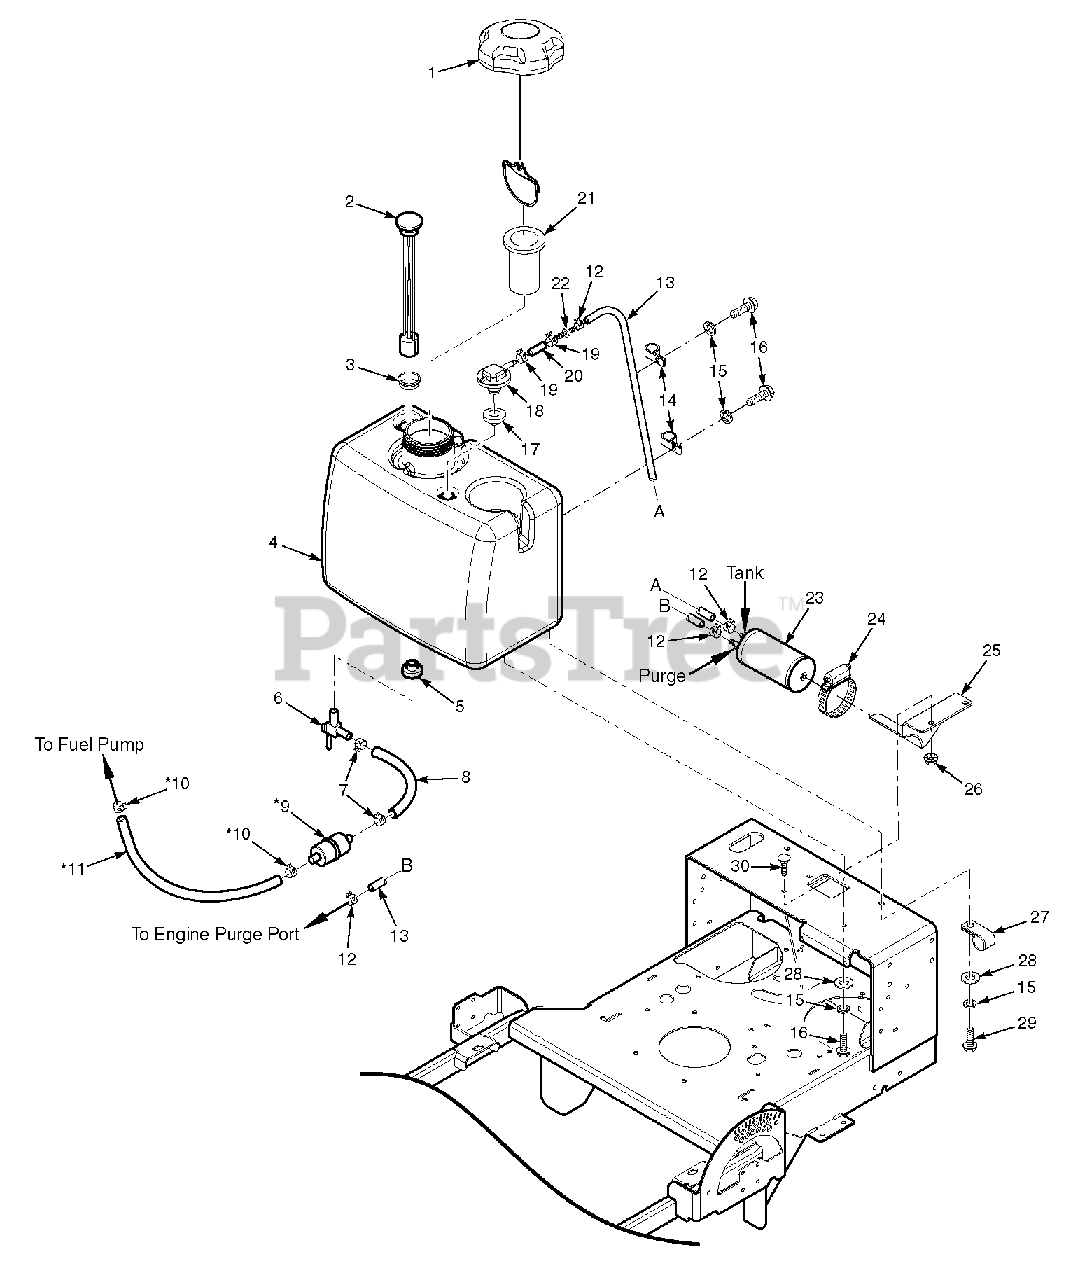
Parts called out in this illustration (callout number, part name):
1	Fuel Cap w/ Tether
2	Fuel Gauge Assembly
3	Seal, Fuel Gauge
4	Fuel Tank Assembly
5	Bushing, .56 Dia. Viton
6	Ball Valve w/Screen
7	Clamp, Fuel Hose
8	Fuel Hose, 1/4" ID
9	Fuel Filter
10	Clamp, Fuel Hose
11	Fuel Hose
12	Clamp, Vapor Recovery Hose 3/16"
13	Hose, Vapor Recovery 3/16"
14	Clamp, 3/8"
15	Lockwasher, 5/16" Spring
16	Bolt, Hex Head 5/16-18 x 3/4"
17	Grommet, Viton
18	Fitting, Remote Vent
19	Clamp, Fuel Hose 7/32" ID
20	Hose, Vapor Recovery 1/4"
21	Tube, Fuel Tank Insert - 4"
22	Mender, 1/4 x 3/16 w/.02 Hole
23	Carbon Canister
25	Bracket, Canister Mounting
26	Nut, Serrated Flange 5/16-18
27	Clamp, 1/2"
28	Flatwasher, 5/16-.375 x .875 x .083
29	Bolt, Hex Head 5/16-18 x 1"
30	Bolt, Carriage 5/16-18 X 3/4"
